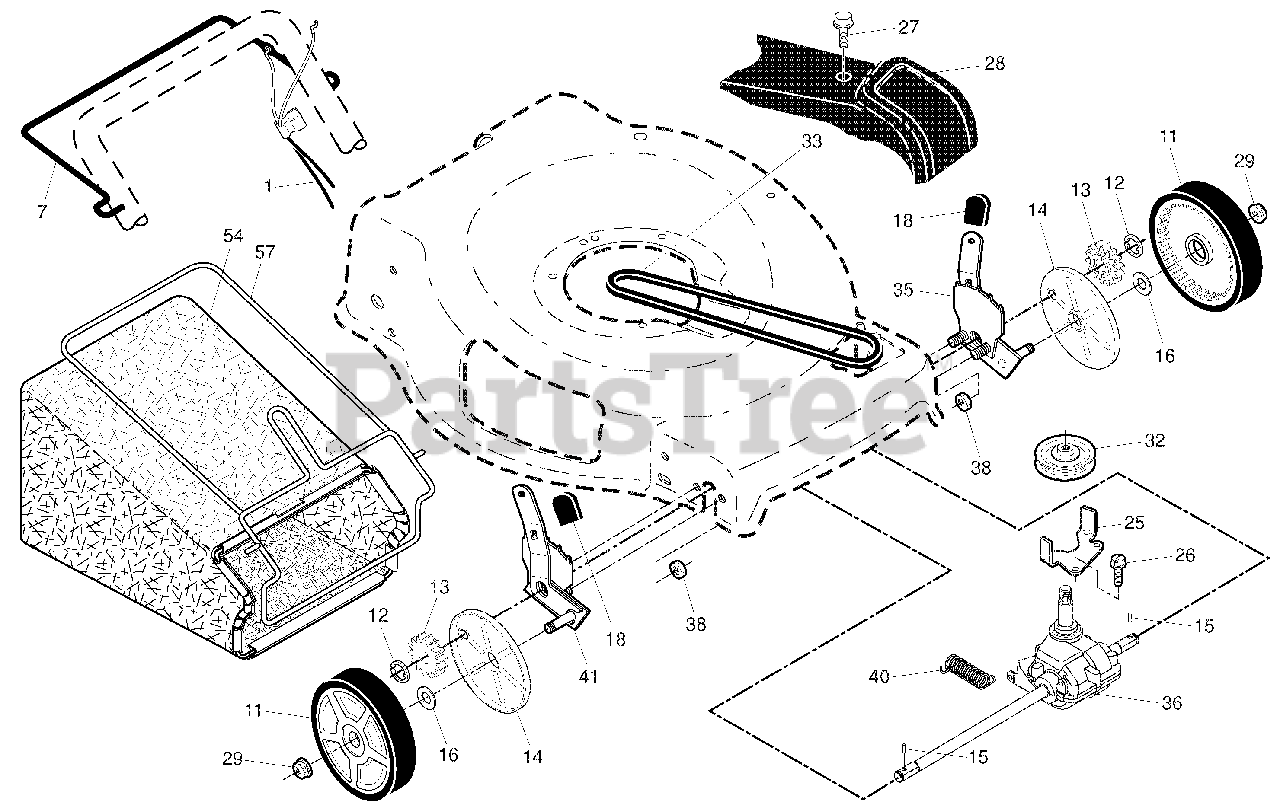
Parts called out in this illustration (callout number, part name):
1	CABLE, DRIVE CONTROL
7	CONTROL BAR, DRIVE
11	WHEEL & TIRE ASSEMBLY
14	DUST COVER
15	Pawl, Drive
16	Washer, Flat 3/8
18	Selector Knob
25	BELT KEEPER
26	SCREW, HI-LO THREAD #12 X 5/8
27	Pan Head Tapping Screw #10-24
28	DRIVE COVER
29	Nut, Hex
32	DRIVE PULLEY
35	WHEEL ADJUSTER, FRONT LH W/BRG
36	GEARCASE ASSEMBLY, COMPLETE
38	LOCKNUT, HEX 1/4-20
41	WHEEL ADJUSTER, FRONT RH W/BRG
54	GRASSBAG
57	FRAME, GRASSBAG
